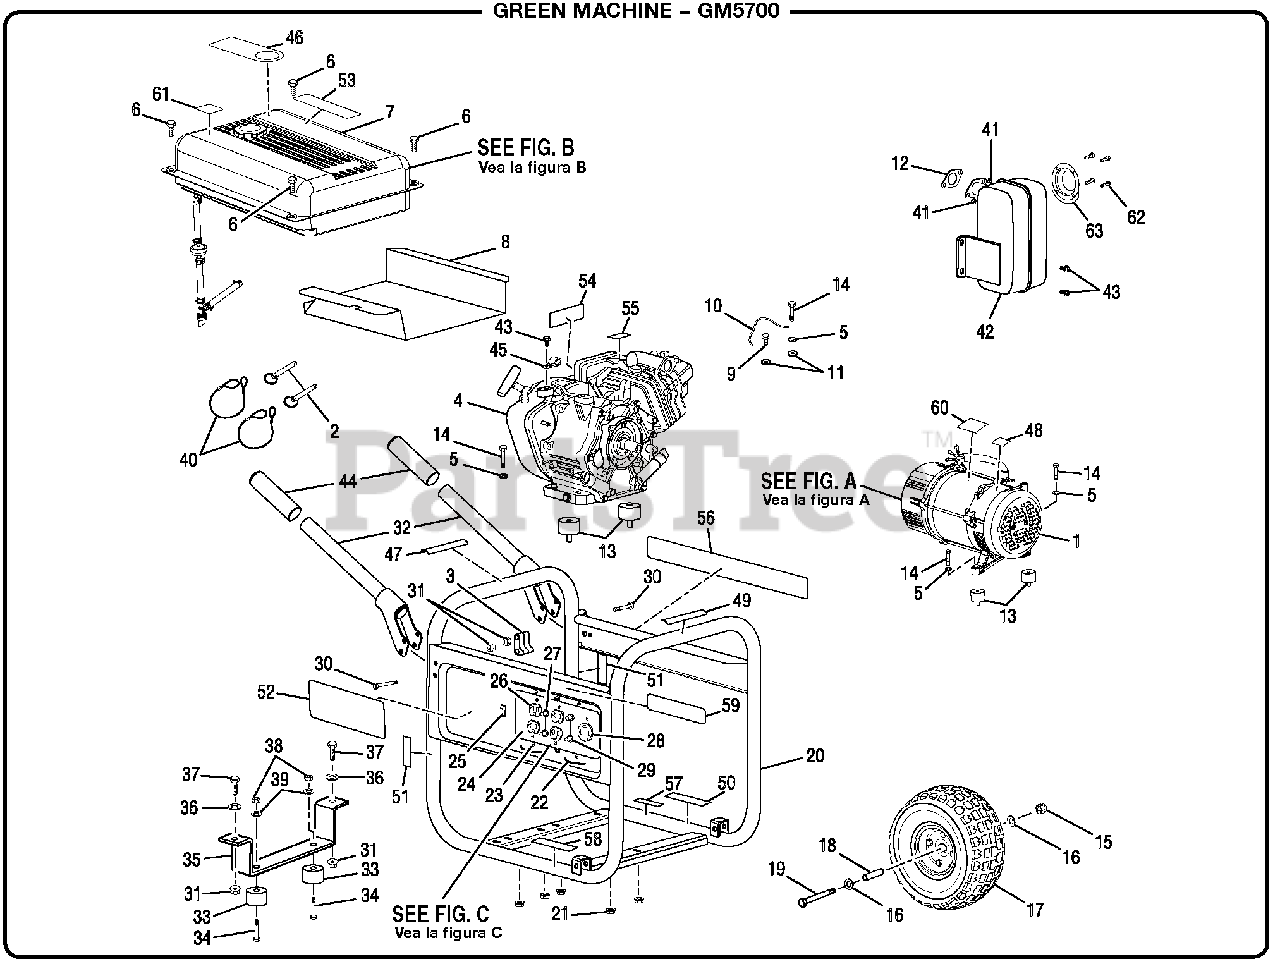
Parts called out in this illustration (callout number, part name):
1	Generator Head Assembly (See Figure A)
2	Handle Lock Pin
3	Handle Bracket Spacer
4	Engine (Yamaha OHV)
5	Lock Washer (5/16 in.)
6	Screw (1/4-20 x 1 in.)
7	Fuel System Assembly (See Figure B)
8	Heat Shield
9	Bolt (5/16-18 x 3/4 in., Hex. Hd.)
10	Ground Wire Assembly
11	Washer (5/16 in., External Star)
14	Bolt (5/16-18 x 1 1/2 in., Hex Hd.)
15	Lock Nut (3/8-16)
16	Washer (3/8 in.)
17	Wheel (10 in.)
18	Wheel Spacer
19	Bolt (3/8-16 x 5-1/4 in.)
20	Frame Assembly
21	Flange Nut (5/16-18, Hex Hd.)
22	Cord Retainer
23	Screw (6-20 x 0.38 in.)
24	Control Panel Assembly (See Figure C)
25	Switch, Engine Stop
26	Recepticle (120 V, 20 Amp)
27	Circuit Breaker 20 Amp Single Pole
28	Recepticle (240 V, 30 Amp)
29	Circuit Breaker 25 Amp Single Pole
30	Bolt (1/4-20 x 1 in.)
31	Lock Nut (5/16-18)
32	Handle Assembly (Inc. Key No. 44)
33	Rubber Foot
34	Bolt (1/4-20 x 1/2 in.)
35	Front Foot Bracket
36	Washer (5/16 in.)
37	Bolt (5/16-18 x 1 in., Hex Hd.)
38	Lock Nut (1/4-20)
39	Washer (1/4 in.)
43	Bolt (5/16-24 x 5/8 in.)
44	Handle Grip
45	J Clamp (1/2 in.)
46	Danger Hang Tag
47	Fire Danger Label
48	Ground Label
49	Ground Warning Label
50	Hot Surface Label
51	Lock Pin Label
52	Logo Label
53	CPSC Label
54	Start Label
55	Choke Label
56	Danger Label
57	Combustion Warning Label
58	Engine Lubricant Label
59	Yamaha Label
60	Data Label
61	E85 Label
62	Screw (8-32 x 3/8 in., Pan Hd.)
63	Spark Arrestor
